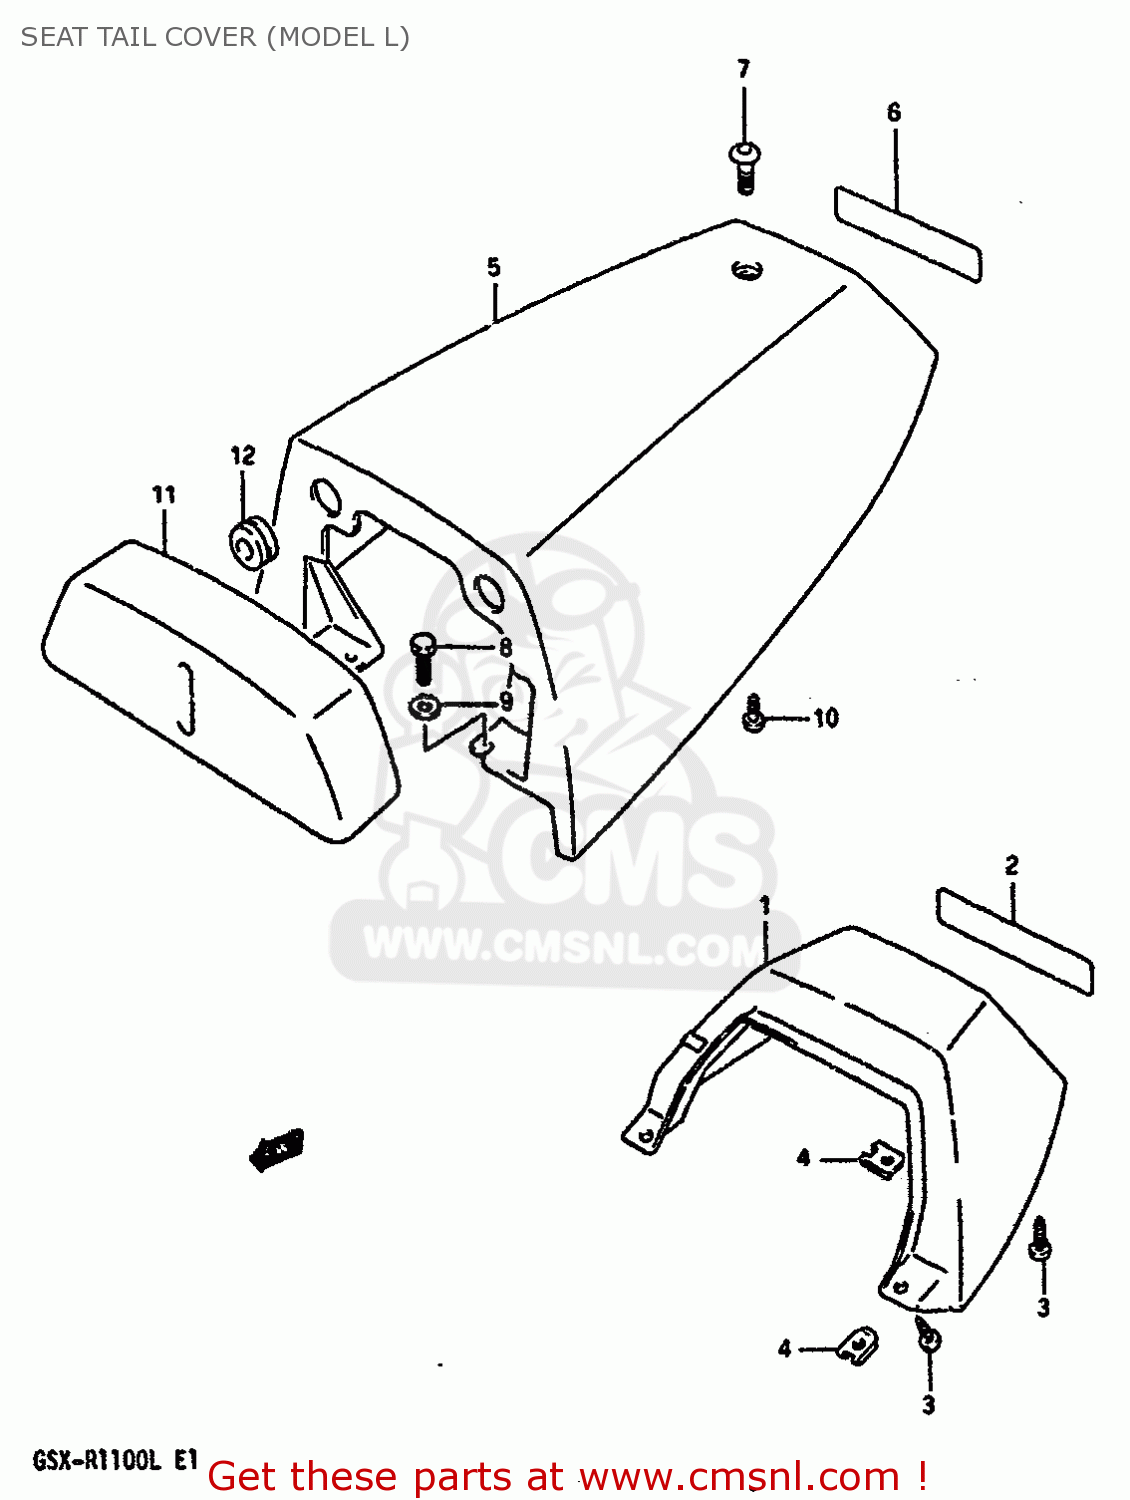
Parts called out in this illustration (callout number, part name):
1	COVER COMP,SEAT TAIL
2	EMBLEM
3	SCREW
4	NUT
5	BOX ASSEMBLY,SEAT TAIL
6	EMBLEM
7	SCREW(6X16)
8	BOLT,M6X1X20
9	WASHER, LOWER
10	SCREW
11	BOX ASSEMBLY,SEAT TAIL
12	CUSHION
13	EMBLEM
14	SCREW(6X16)
15	BOLT,M6X1X20
16	WASHER, LOWER
17	SCREW
18	BACKREST,SEAT
19	CUSHION
